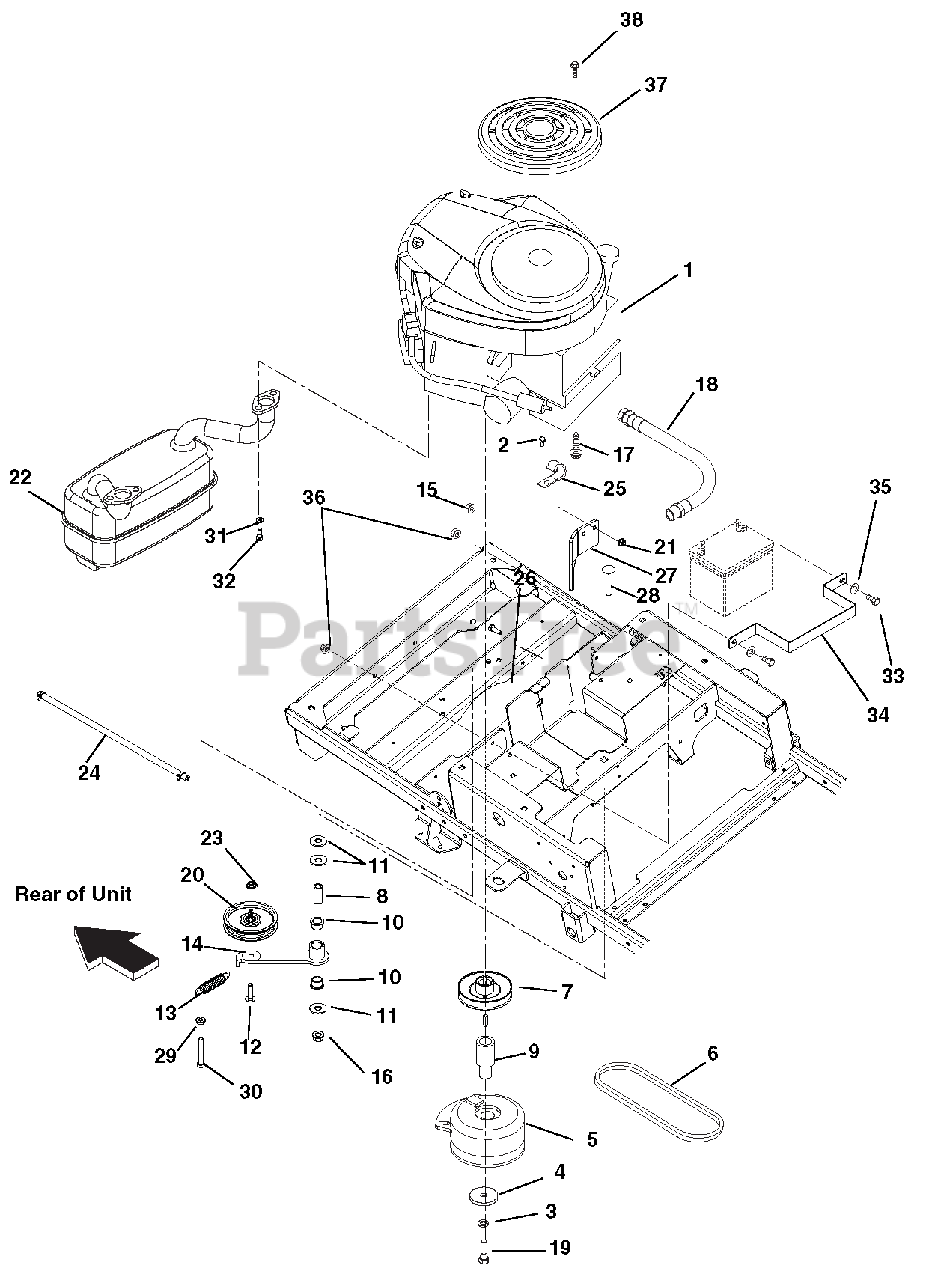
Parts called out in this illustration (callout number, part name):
1	ENGINE, 18HP V-TWIN CE
2	@SCR-TAP .25-20X.37 HWH YWZ TR
3	@WSHR-LK .44X.109 REG YWZC
4	WSHR-FL-STL .469X2.00X.25 YWZC
5	CLUTCH, MS WITH BRAKE
6	V-BELT, HA-WRAPPED
7	PLY-V 4.5X1.5 AB SECTION W/KEY
8	BSHG-SLV .500X.750X1.560
9	EXT-CRANKSHAFT LOWER
10	BSHG-FLG 0.75X0.875X.625X1.125
11	@WSHR-FL-STL.563X1.38X.109YWZC
12	@BLT-RDHDSQNK .38-16X1.50 G5YZ
13	SG-TENS .105X.812X3.88 WLD 15
14	WMT, GROUND DRIVE IDLER ARM
15	@NUT-LK-NYL-FLG .38-16 YWZC
16	@NUT-LK-TOP-FLG .50-13 YWZC
17	@SCR-TAP .38-16X1.00 HWH TR YZ
18	HOSE, HYD .38-11-0K M6N0-F6J0
19	BLT-HEX .44-20X4.50 GR8 YWZC
20	ASM, 4" IDLER (.75 WIDE)
21	@NUT-LK-NYL-FLG .31-18 YWZC
22	MUFFLER - TWIN BRIGGS
23	@NUT-LK-TOP-FLG .38-16 YWZC
24	ASM, FUEL HOSE
25	J-CLAMP
26	@BLT-HEX .31-18X1.00 GR5 YWZC
27	CLUTCH STOP
28	@BLT-RDHDSQNK .50-13X2.50 G5YZ
29	@NUT-SPNLK-FLG .375-16 YWZC
30	@BLT-HEX .38-16X2.50 GR5 YWZC
31	@WSHR-LK .31X.078 REG YWZC
32	SCR-CAP .31-18X.75 S/HD
33	@BLT-HEX .25-20X.75 GR5 YWZC
34	BRKT, BATTERY HOLD DOWN
35	@WSHR-FL-STL.281X.62X.065 YWZC
36	NUT-KEPS .250-20
37	GUARD, BRIGGS ENGINE
38	SCREW, 8-16X.87 PHPAN 3 LOBE
